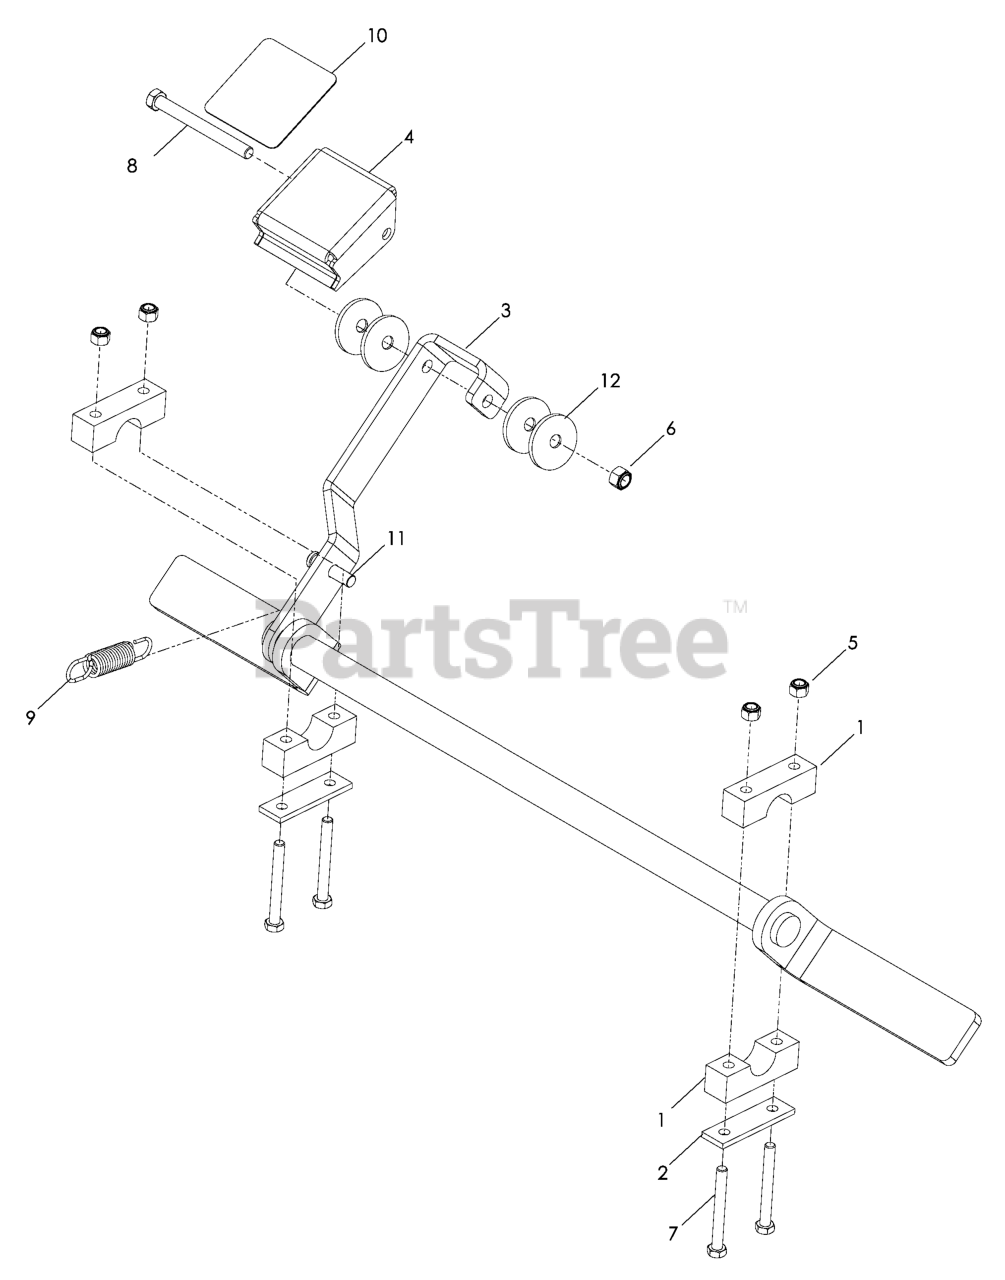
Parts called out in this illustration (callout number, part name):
1	PILLOW BLOCK
2	REINFORCEMENT BAR
3	PARK BRAKE
4	PEDAL, BLACK
5	NUT 5/16 NYLOC
6	NUT 3/8-16 NYLOC
7	HCS 5/16C X 2-3/4
8	HCS3/8-16.X
9	SPRING, EXTENSION
10	ANTI-SKID PAD
11	CLEVIS PIN, 3/8 X 1 1/2
12	WASHER, FRICTION
